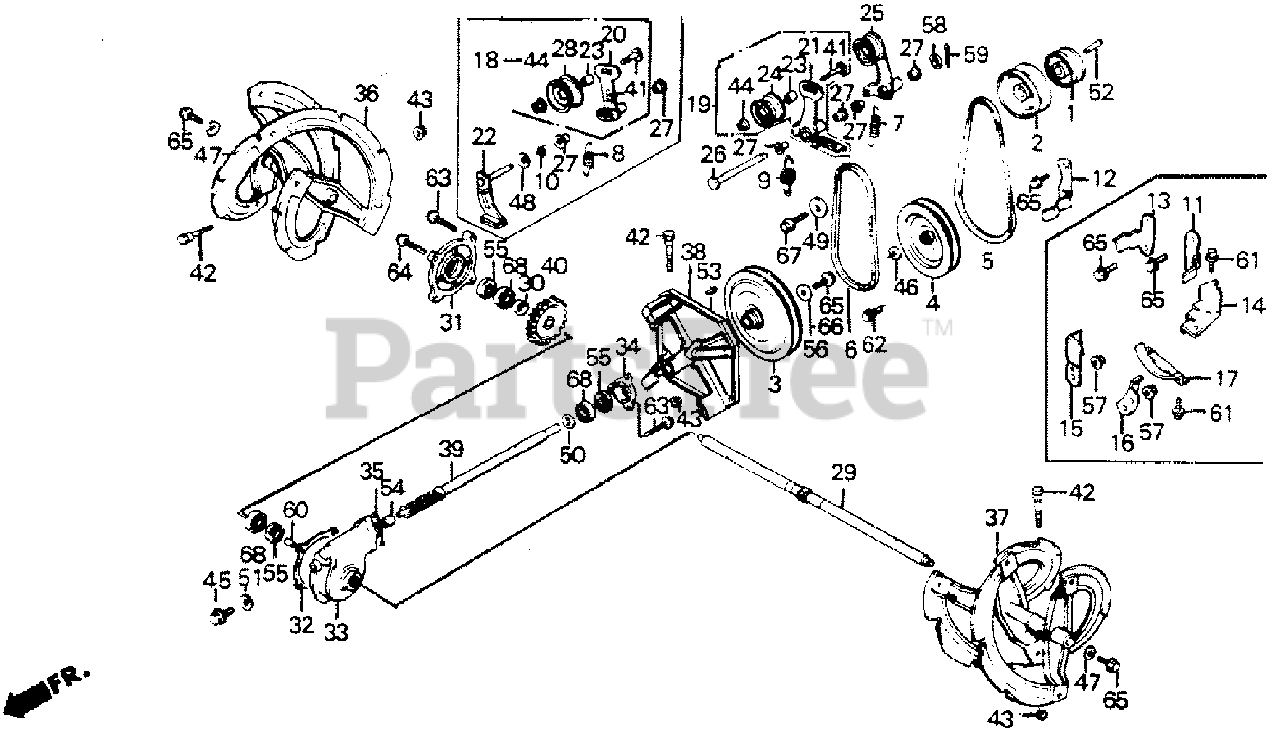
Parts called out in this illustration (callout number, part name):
1	PULLEY, WHEEL DRIVEN
2	PULLEY, AUGER DRIVE
3	PULLEY, AUGER DRIVEN
4	PULLEY, WHEEL DRIVEN
5	V-BELT (SA-30)
6	V-BELT (LB-33)
7	SPRING, TENSIONER RETURN (NOT AVAILABLE)
8	SPRING, TENSIONER RETURN (NOT AVAILABLE)
10	SPRING, BRAKE ARM
11	STOPPER, R. BELT
13	STOPPER, L. BELT
14	GUIDE, BELT
15	STOPPER, L. BELT
16	STOPPER, R. BELT
17	STOPPER, BELT (WHEEL)
18	ARM ASSY., AUGER TENSION
20	ARM, AUGER TENSION
22	ARM, AUGER BRAKE
23	COLLAR, ROLLER
25	ARM, TENSION (NOT AVAILABLE)
27	BUSH, TENSIONER ARM
29	SHAFT, AUGER
30	COLLAR, DISTANCE
31	COVER, AUGER TRANSMISSION (NOT AVAILABLE)
32	GASKET, AUGER TRANSMISSION
33	CASE, L. AUGER TRANSMISSION (NOT AVAILABLE)
34	CAP, AUGER CASE (NOT AVAILABLE)
35	GASKET, AUGER CASE
38	BLOWER (12") (NOT AVAILABLE)
39	GEAR, DRIVE (NOT AVAILABLE)
39	GEAR, DRIVE (12") (NOT AVAILABLE)
40	GEAR, DRIVEN (NOT AVAILABLE)
41	BOLT, ROLLER
42	BOLT, LOCK
43	NUT, SELF-LOCK (6MM)
44	NUT, SELF-LOCK (8MM)
45	BOLT, DRAIN PLUG
46	WASHER, CAMSHAFT SIDE
47	WASHER (8MM)
48	WASHER, BRAKE ARM
49	WASHER, LOCK (8MM)
50	WASHER, THRUST (27X20X1.0)
51	WASHER, DRAIN PLUG (10.2MM)
53	KEY, SPECIAL WOODRUFF (16X12)
54	BEARING, NEEDLE (15MM)
55	OIL SEAL (20X32X7)
56	WASHER, SPECIAL (28X8.5X4.0)
57	NUT, FLANGE (6MM)
58	WASHER, FLAT (12MM)
59	PIN, COTTER (3.0X18)
60	PIN A, DOWEL (8X14)
61	BOLT, FLANGE (6X12)
62	BOLT, FLANGE (6X16)
63	BOLT, FLANGE (6X20)
64	BOLT, FLANGE (6X28)
65	BOLT, FLANGE (8X16)
66	BOLT, FLANGE (8X22)
67	BOLT, FLANGE (8X35)
68	BEARING, RADIAL BALL (6004)
